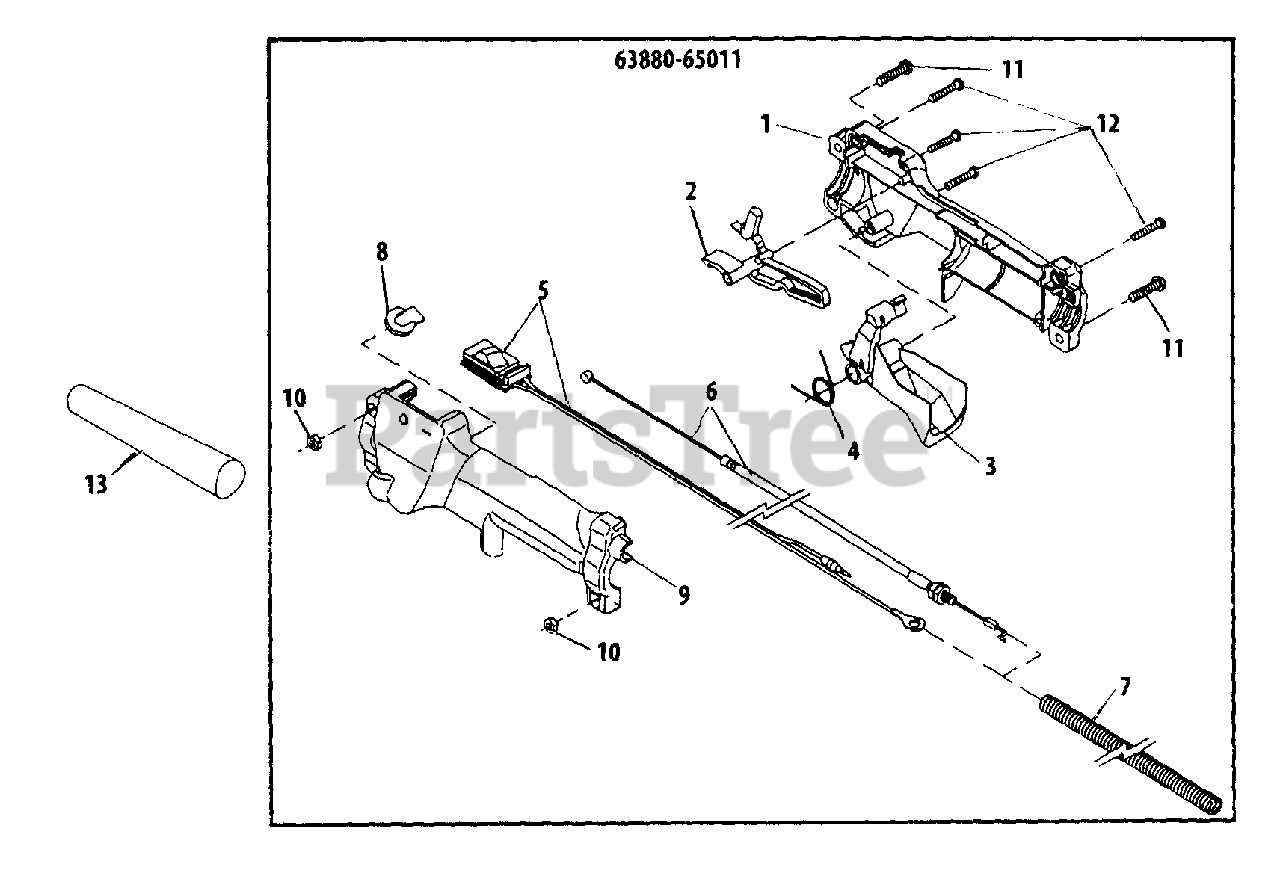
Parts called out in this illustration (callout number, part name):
1	HANDLE, CONTROL - RIGHT
2	LEVER, LOCK
3	LEVER
4	SPRING
5	SWITCH, IGNITION
6	CABLE, THROTTLE
7	TUBE
8	PLUG
9	HANDLE, CONTROL - LEFT
10	NUT - 5
11	SCREW - 5X20
12	SCREW - 4X20 -- TAPPING
13	SPACER
63880-65011	THROTTLE LEVER ASSY
